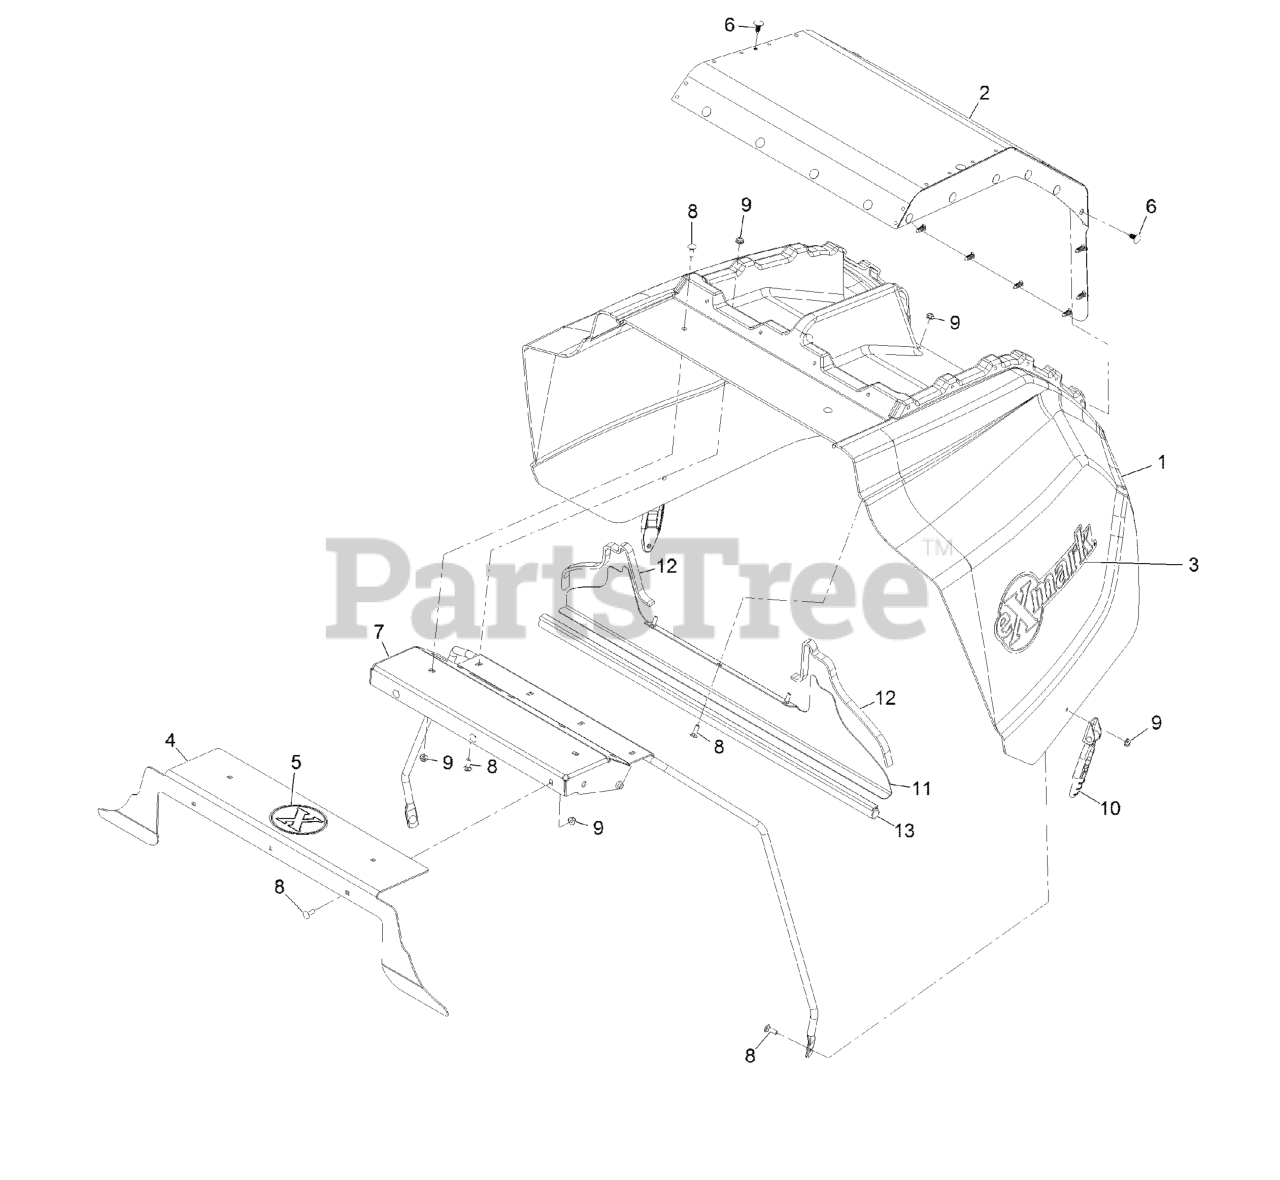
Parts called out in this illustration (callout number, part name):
1	HOOD,LZSD
2	Screen-Intake
3	DECAL-EXMARK
4	Block Off-Hood
5	DECAL-X-LOGO
6	PLUG-PLASTIC
7	SUPPORT-HOOD
8	BOLT-CARR
10	LATCH-RUBBER
11	Plate-Seal
12	SEAL-FOAM
13	Seal-Bulb
